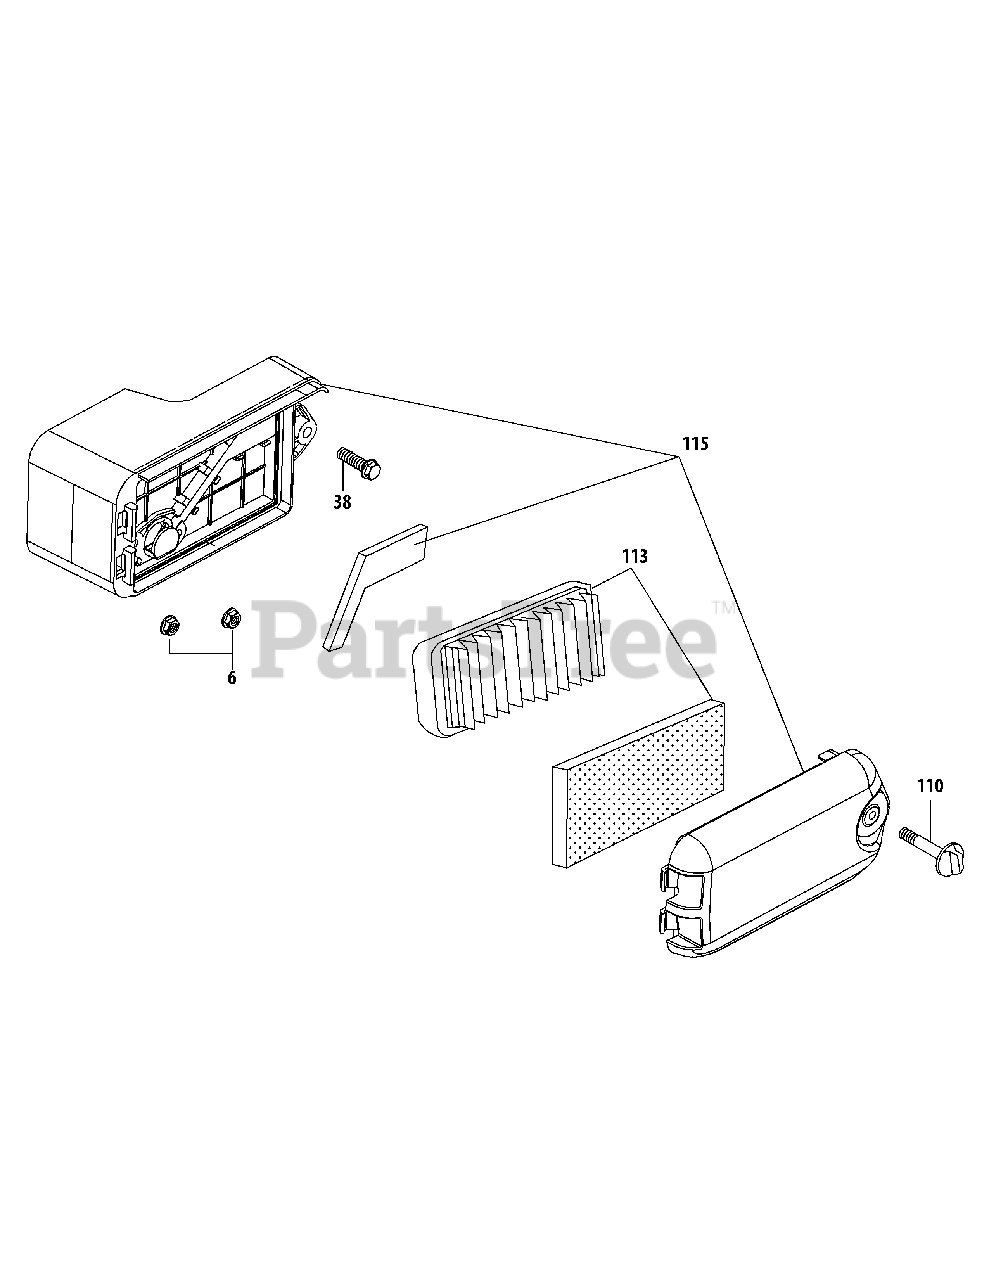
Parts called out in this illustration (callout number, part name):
6	Nut M6X10Mm
38	Bolt M6X35
110	Air Filter Cover Thumb Screw
113	Air Cleaner Filter Kit
115	Air Cleaner Housing Assy Comp
